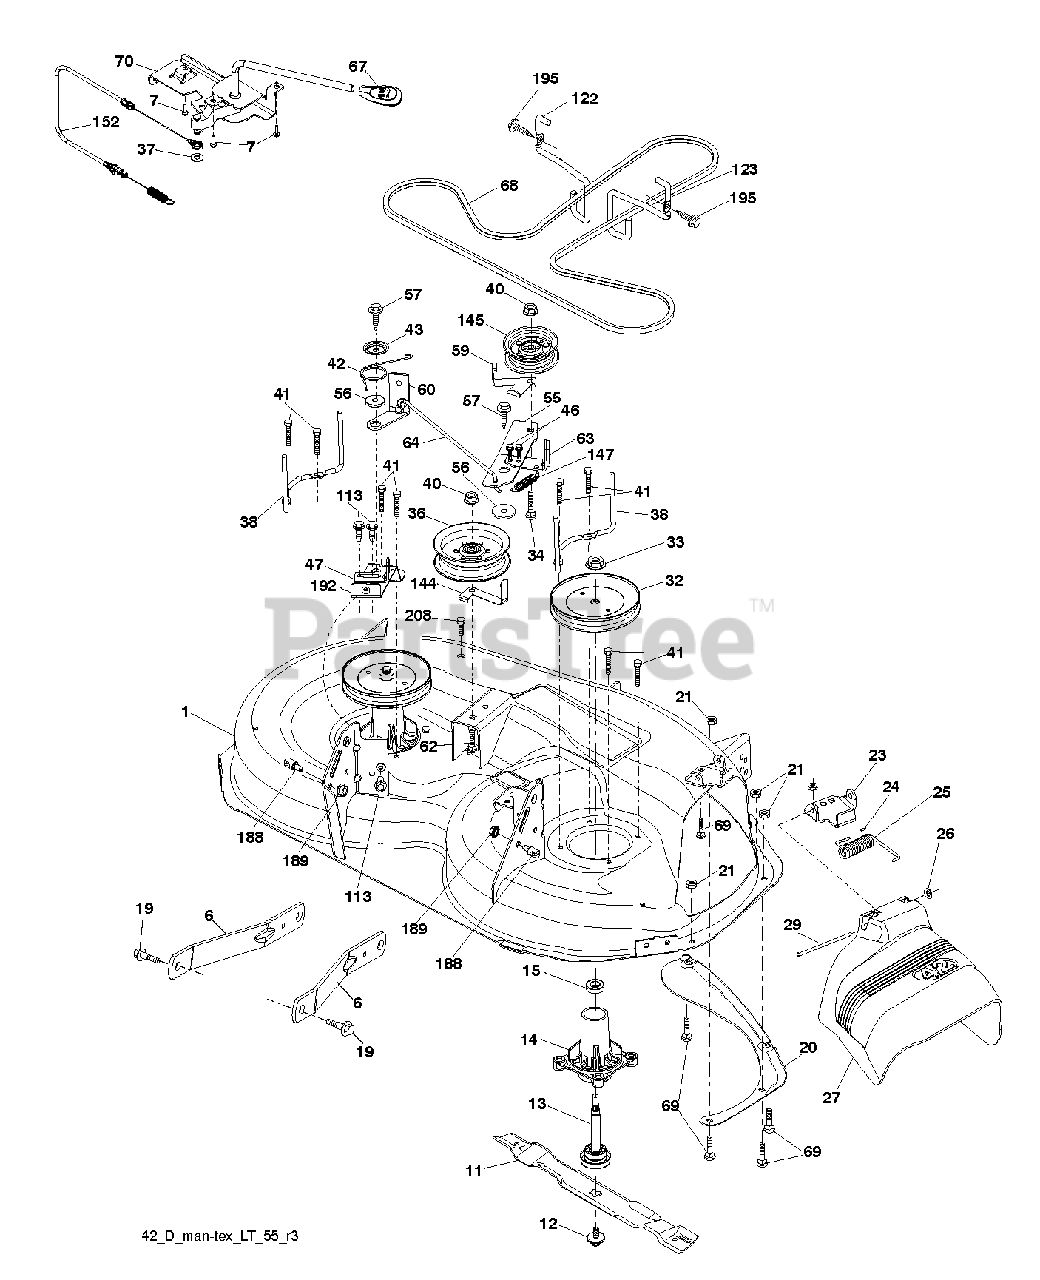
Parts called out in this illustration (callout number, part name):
6	ARM.SUSPENSION.MOWER.R
7	SCREW.#10 X 0.750.BOS (2 2)
11	42" HI-LIFT BLADE
12	Screw, 7/16 X 20 X 1"
13	SHAFT.ASM.MDRL.N/GREASE.38
14	HOUSING.MANDREL.4PT.
19	BOLT.SHOULDER
20	BAFFLE.VORTEX
21	LOCKNUT
23	BRKT.DEFLECTOR.38"2005+
24	CAP-SLEEVE LT
25	SPRING.TORSION.DEFLECT
26	NUT PUSH M
27	SHIELD.DEFLECTOR.MOWER.42"BLAC
29	ROD.HINGE
32	PULLEY.MANDREL.5.438.PD
33	NUT.FLANGE.LOCK.TOP
34	BOLT.3/8-16X1.50
36	PULLEY.IDLER.2006
38	KEEPER.BELT.MANDREL.PULLEY
40	NUT LOCK FLG 3/8-16 UNC
41	Hex Washer Head Bolt, .313-18 X 1.19
42	SPRING.TORSION.BRAKE
43	SRPING.TORSION.RETAINE
46	SCREW.1/4-20X5/8
47	BRKT.CLUTCH.CABLE
55	IDLER.ARM.42"
56	SPACER.RETAINER
57	SCREW 3/8-16X1
59	GUARD, BELT
60	ARM BRAKE MOWER
62	BOLT
64	LINK BRAKE
67	HANDLE.CLUTCH.CABLE.LT
68	BELT.DECK.DRIVE.42"
69	BOLT
70	CLUTCH.ASM.MANUAL.LT.TEX
113	BOLT.5/16HEX.WHS.HD
122	KEEPER BELT ENGINE LH
123	KEEPER BELT RH
144	KEEPER.BELT.MOWER
145	PULLEY.IDLER.48"PRIMARY
147	RETURN SPRING
152	CABLE.MECHANICAL.CLUTCH
188	STUD.FASTNER.W/ANTI-ROTATE
189	NUT LOCK HEX FLANGE 5/16-18
192	BRKT.BRAKE.STAND.LH.
195	SCREW, 3/8-16X3/4
208	SCREW 3/8-16X1/2
